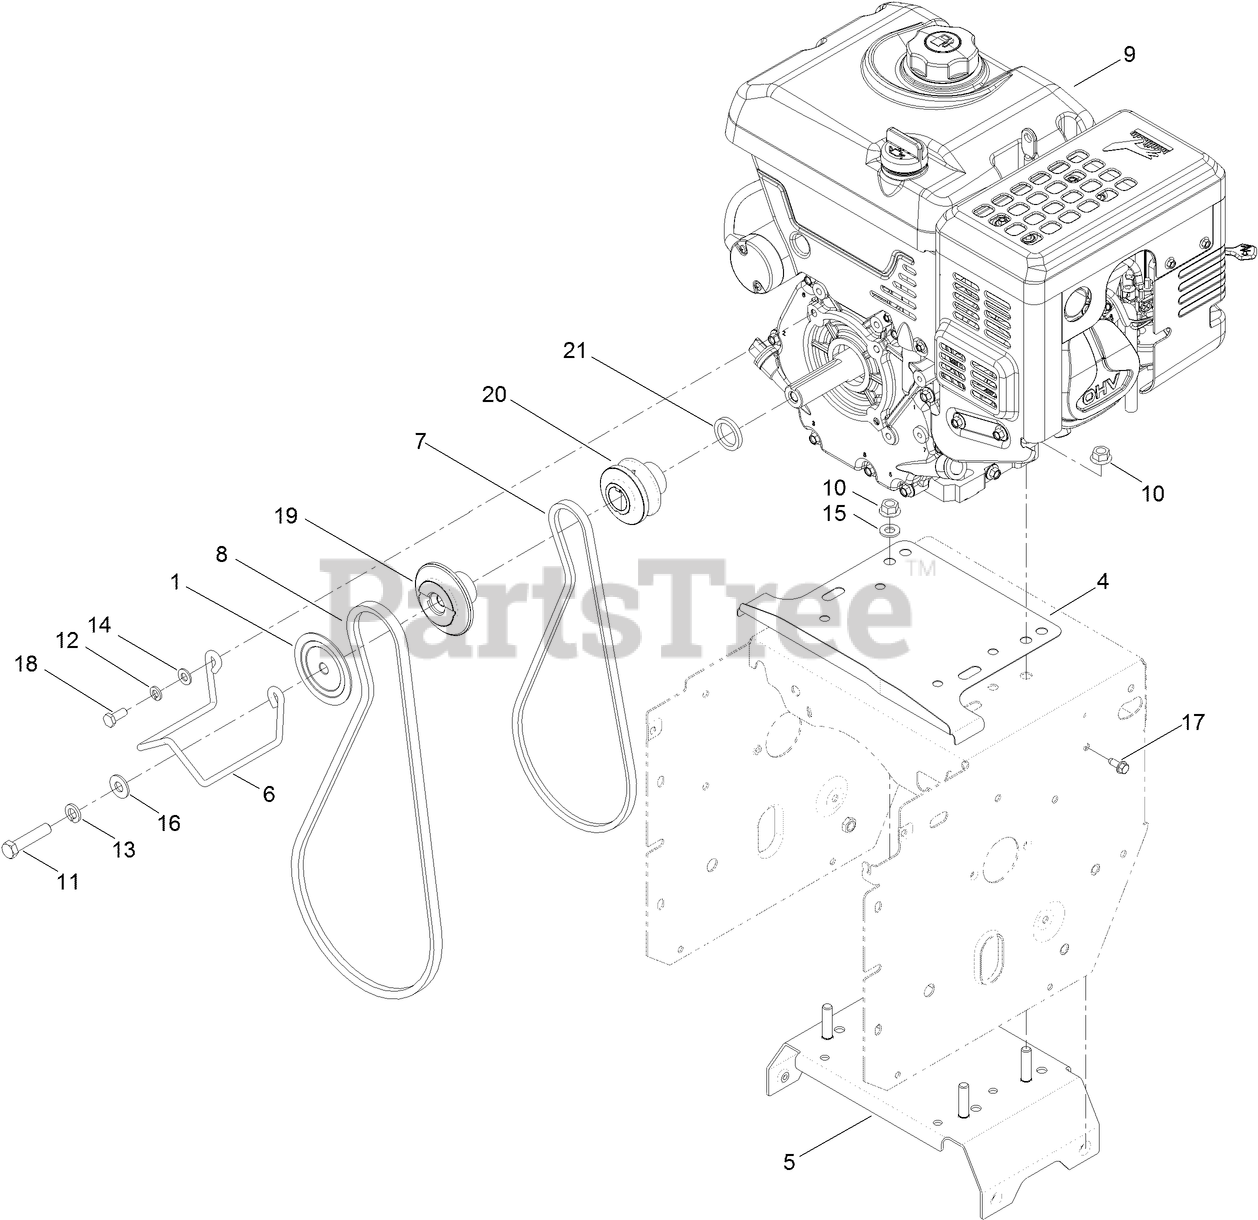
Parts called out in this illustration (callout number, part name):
1	SHEAVE-HALF, IMPELLER
4	SHIELD-DRIVE
5	FRAME BRACE ASM
7	V BELT-TRACTION
8	BELT-V
10	NUT-HF
11	SCREW-HH
12	WASHER-LOCK
13	WASHER-LOCK
14	WASHER-PLAIN
15	WASHER-FLAT
16	WASHER-FLAT
17	SCREW-HWH
18	SCREW-HH
19	PULLEY-ENGINE, IMPELLER
20	PULLEY-TRACTION
21	SPACER-HARDENED
